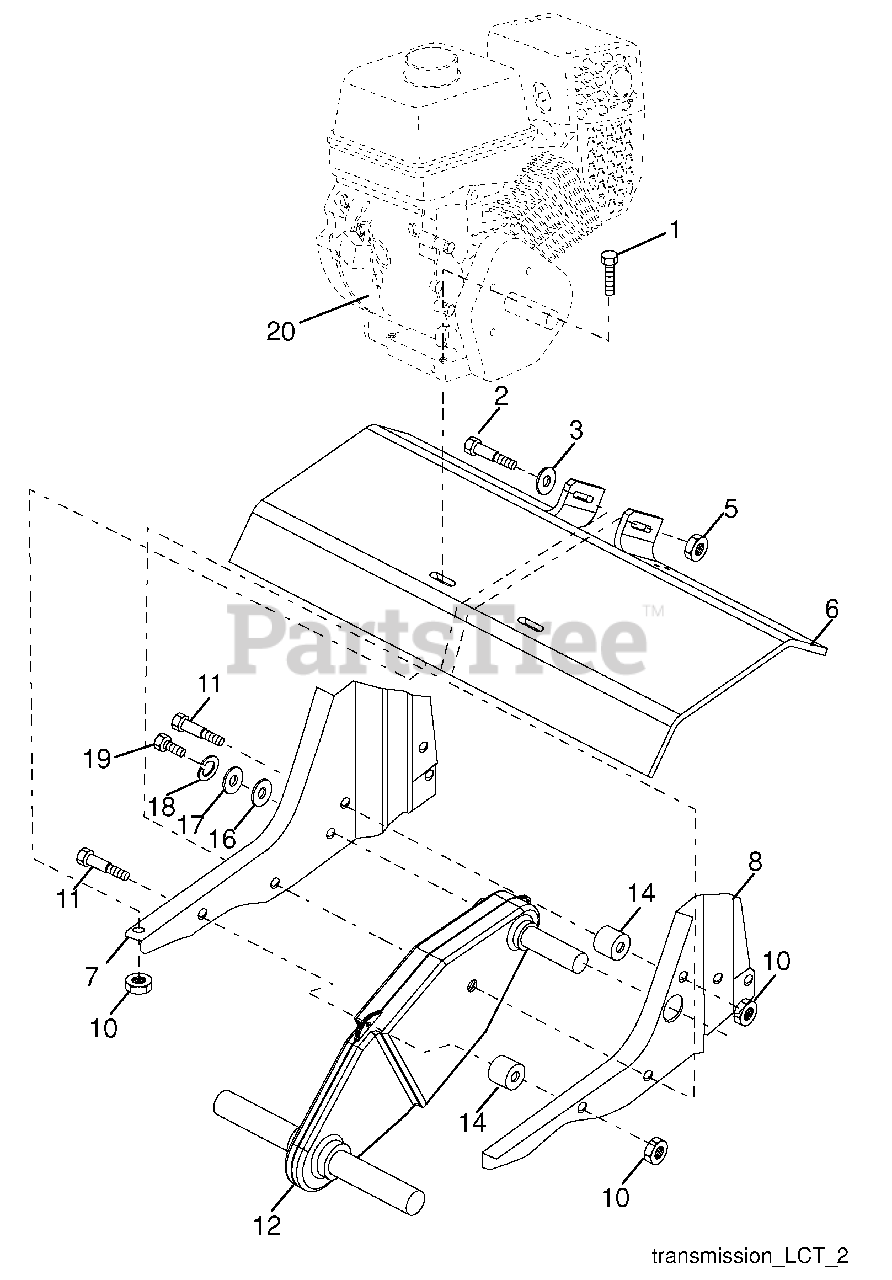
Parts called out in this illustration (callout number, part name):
1	Bolt, Hex Head, Gr. 25/16-18 x 1-1/2
2	Bolt, Hex Head, 3/8-16 x 3-1/4
3	Washer, 3/32 x 13/16 x 11
5	Nut, Hex, Flangelock 3/8-16
7	Bracket, Engine, R.H.
8	Bracket, Engine, L.H.
10	Nut, Hex, Flangelock
11	Bolt, Shoulder
12	Transmission
14	Spacer, Split
16	Washer, 9/32 x 7/8 x 12 Ga.
17	Washer, 9/32 x 1-1/4 x 16 Ga.
18	Washer, Lock 1/4
19	Bolt, Hex Head, Gr. 5 1/4-28 x 3/4
